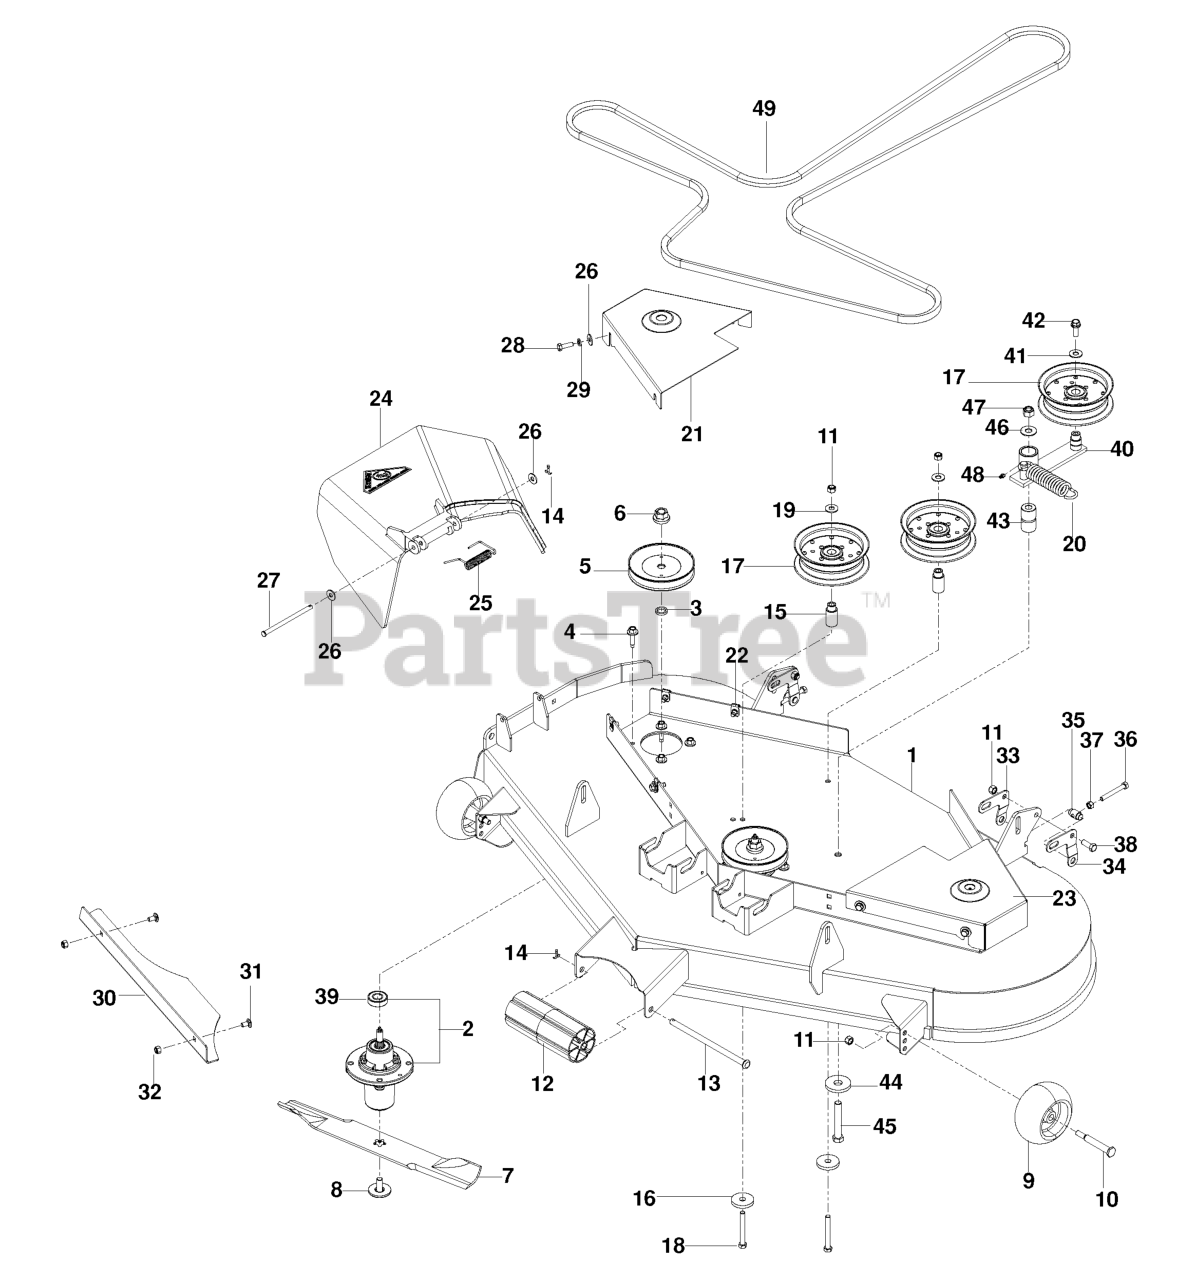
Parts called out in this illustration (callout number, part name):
1	DECK.FAB.W/DECALS.52".MZ.ORANG
2	MANDREL.DECK.ASSEMBLY
3	WASHER-SPACER
4	WASHER HEAD SCREW
5	PULLEY
6	LOCKNUT - 9/16
7	BLADE, 18"
8	BLADE BOLT ASSY-7/16" TB REPL
9	GAUGE WHEEL
10	SHOULDER BOLT 1/2X2-5/8 ZD SPE
11	NUT 3/8-16 NYLOC
12	NOSE ROLLER 48"
13	ROD.ROLLER.NOSE.NARROW.48"
14	RP_COTTER PIN 1/8 X 3/4
15	IDLER BUSHING
16	SPINDLE WASHER
17	PULLEY, IDLER
18	HCS 3/8C X 3
19	WASHER 3/8 FLAT
21	BELT SHIELD, RIGHT 52, ORG
22	U-CLIP 5/16-18 NUT RETAINER
23	BELT SHIELD, LEFT 52, ORG
24	DISCHARGE CHUTE 52"
25	SPRING - TORSION
26	WASHER 5/16 FLAT
27	PIN-CLEVIS 5/16 DIA X 5.19 ZD
28	HCS 5/16C X 1
29	WASHER.LOCK.HVY.HLCL.SPR.5/16
30	CONFINEMENT PLATE, 52"
31	CARRIAGE BOLT 5/16C X 5/8"
32	NUT 5/16 NYLOC
33	PITCH, ADJUST, RT
34	PITCH, ADJUST, LT
35	TRUNION, PITCH
36	HCS 5/16-18 X 2 1/2 TPBLT
37	NUT 5/16C HEX
38	HCS 3/8-16X1.GRD.5.ZD
39	BEARING, BALL
41	WASHER 3/8 FLAT
42	4CS 3/8C X 1 SERRATED HEAD
43	PIVOT BUSHING
44	WASHER, SUPPORT
45	HCS 1/2C X 3 1/4
46	WASHER 1/2 FLAT
47	NUT 1/2-13 HEX NYLOC ZD
48	ZERK
49	BELT, B, 148.5
